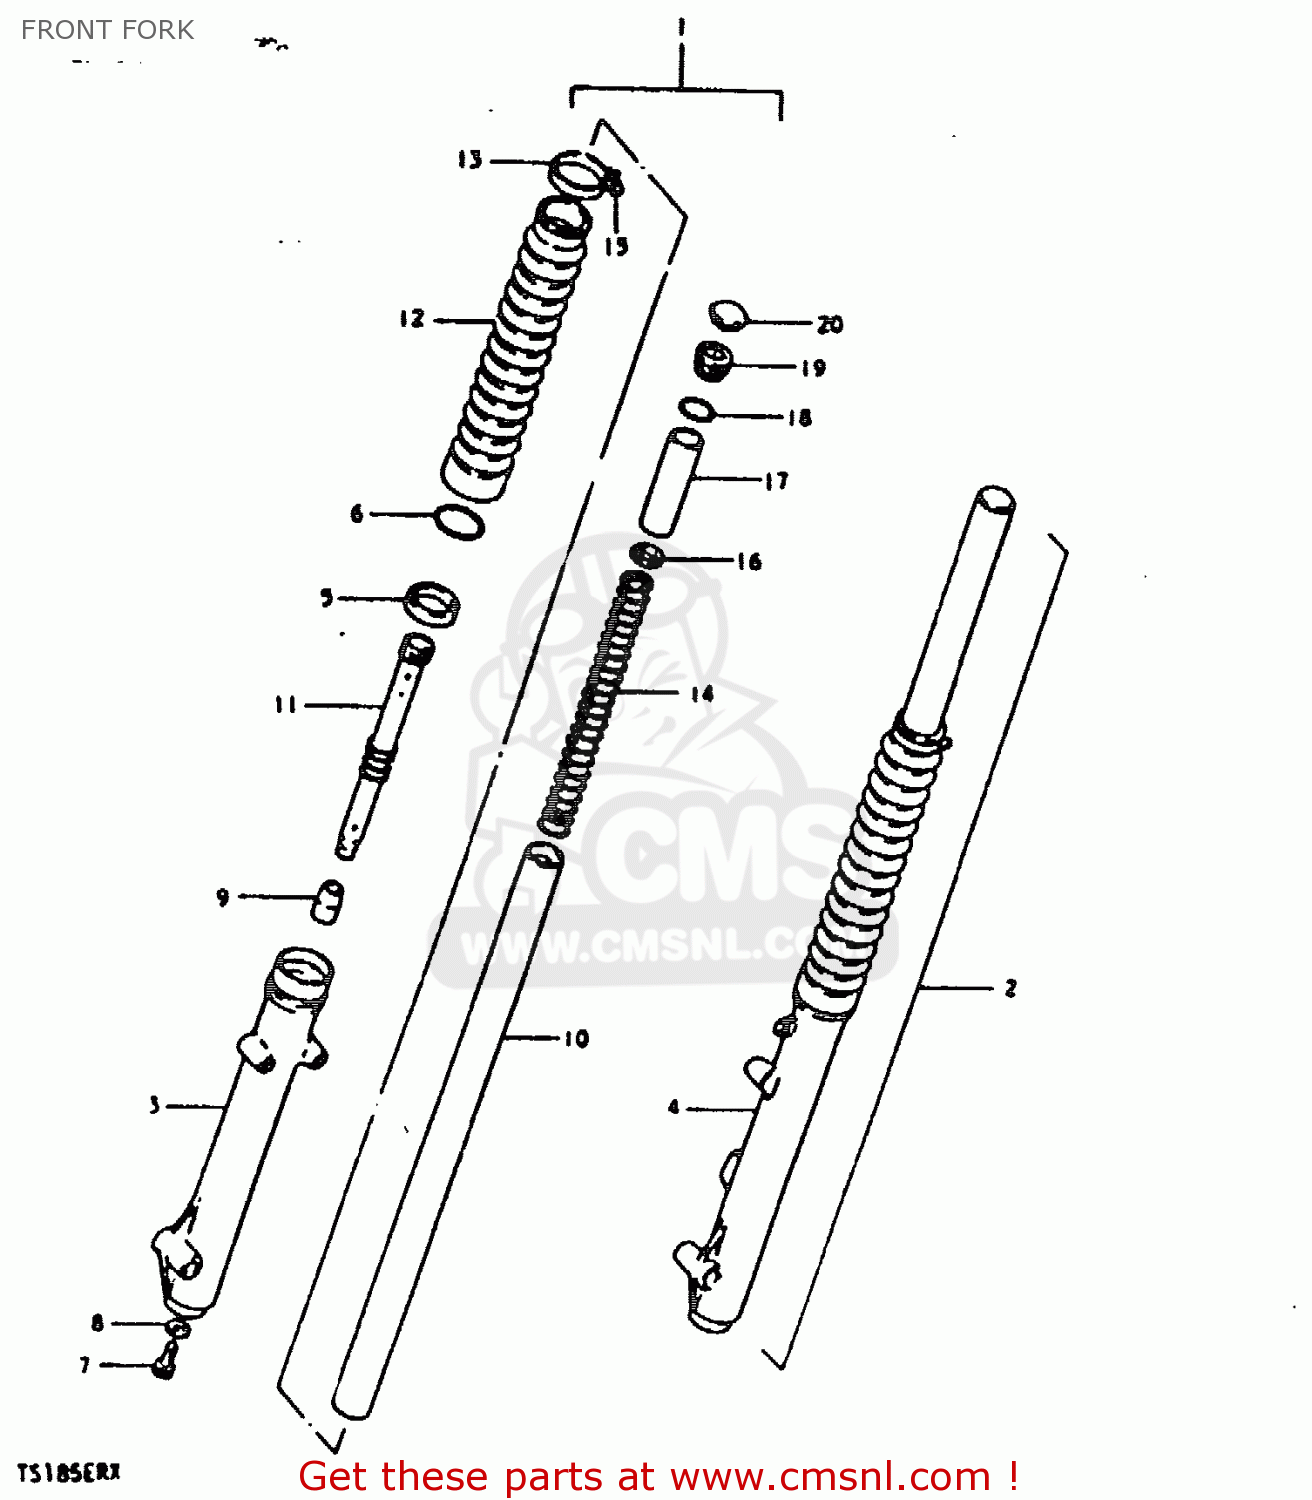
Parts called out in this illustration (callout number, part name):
1	DAMPER ASSY,FR FORK,R
2	DAMPER ASSY,FR FORK,L
3	TUBE,OUTER,R
4	TUBE,OUTER,L
5	SEAL,OIL
6	RING,STOPPER
7	BOLT,FORK CYLINDER(10X25)
8	GASKET (NAS)
9	PIECE,OIL LOCK
10	TUBE,INNER
11	CYLINDER
12	BOOT (BLACK)
13	BAND
14	SPRING
15	SCREW
16	GUIDE,SPRING COVER
17	SPACER,SPRING
18	O-RING,FORK INNER TUBE
19	CAP
20	CAP,FRONT FORK
